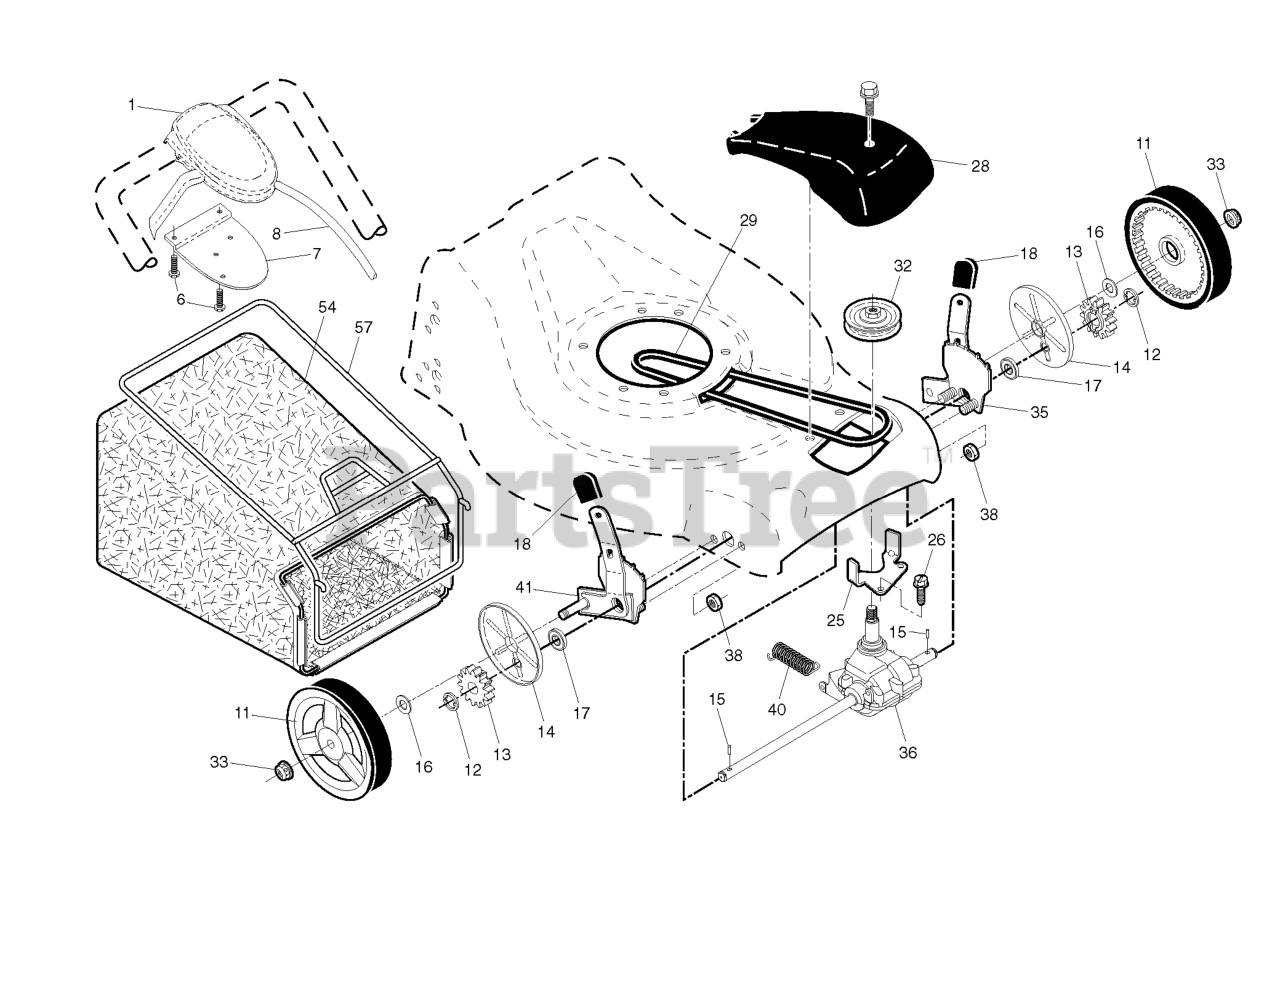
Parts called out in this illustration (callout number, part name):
1	CONTROL.DR.QW.21FGD.BS.GY/BLK
6	SCREW, PHILLIPS HEAD 10 X 5/8
7	BRACKET.DRIVE.CONTROL.MOUNT.BL
8	CABLE ASSEMBLY, DRIVE
11	WHEEL.8X1.75.H3SPK.RAD3.GY.BU3
12	E-RING 7/16 RE
13	PINION.14.TEETH.FGD
14	COVER.DUST.WHEEL
15	PAWL, DRIVE
16	WASHER FLUT
17	BEARING
18	SELECTOR KNOB
25	BELT KEEPER
28	COVER.DRIVE.ASM.185579.CE.WALK
29	BELT.DRIVE.FG
32	RP PULLEY.DRIVE.EZ
33	NUT.HEX.FLANGE.3/8-16.LO(3 2)
35	KIT ADJUSTER ASM.438151.
36	TRANSMISSION.21.FGD.HT.VST
38	LOCKNUT.NYLOC.1/4-20
41	KIT ADJUSTER ASM.438148
54	Grassbag Assembly
57	FRAME.GBAG.21.FWGD
